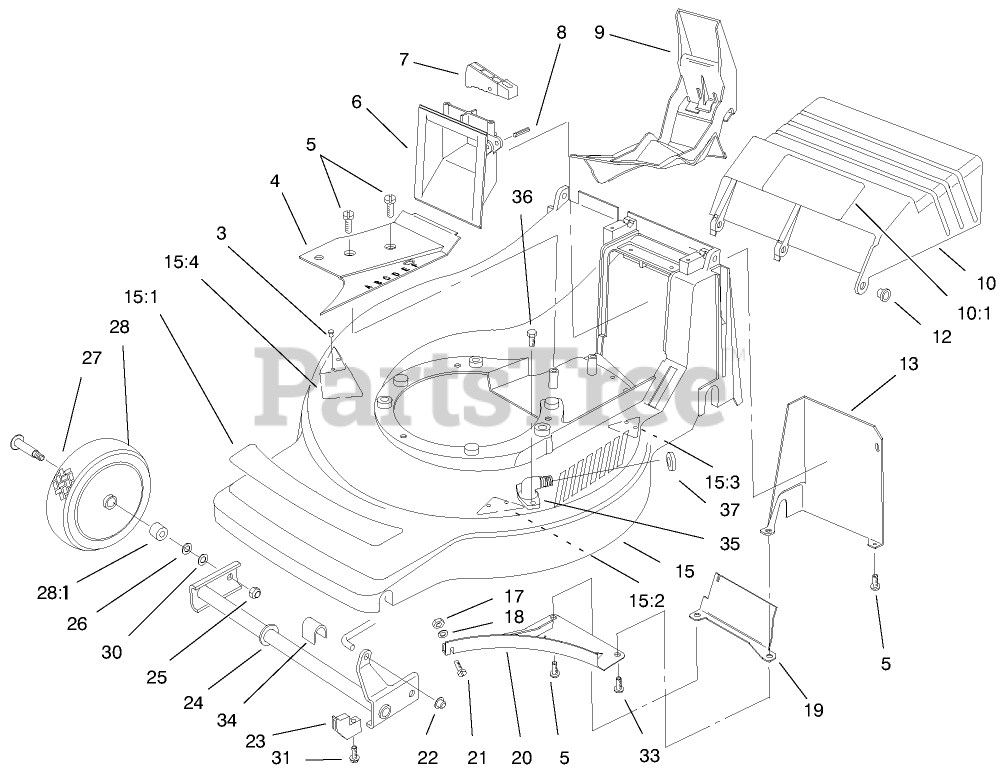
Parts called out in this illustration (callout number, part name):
1	Decal-Deck
4	COVER - BELT
5	SCREW-RH
6	GRIP-LOWER
12	BUSHING-DOOR
13	COVER-SHIELD
15:1	KICKER
15:2	KICKER
15:3	KICKER
15:4	SCREW-PPH
17	NUT-LOCK, NI
18	WASHER-FLAT
19	BAFFLE-BAGGER, REAR
20	BAFFLE
21	SCREW-PPH
22	NUT-PUSH
23	RETAINER-AXLE
24	AXLE-FRONT
26	WASHER
28	WHEEL-FRONT
28:1	BUSHING
30	WASHER-SPRING
36	SCREW-HWH
37	O-RING
